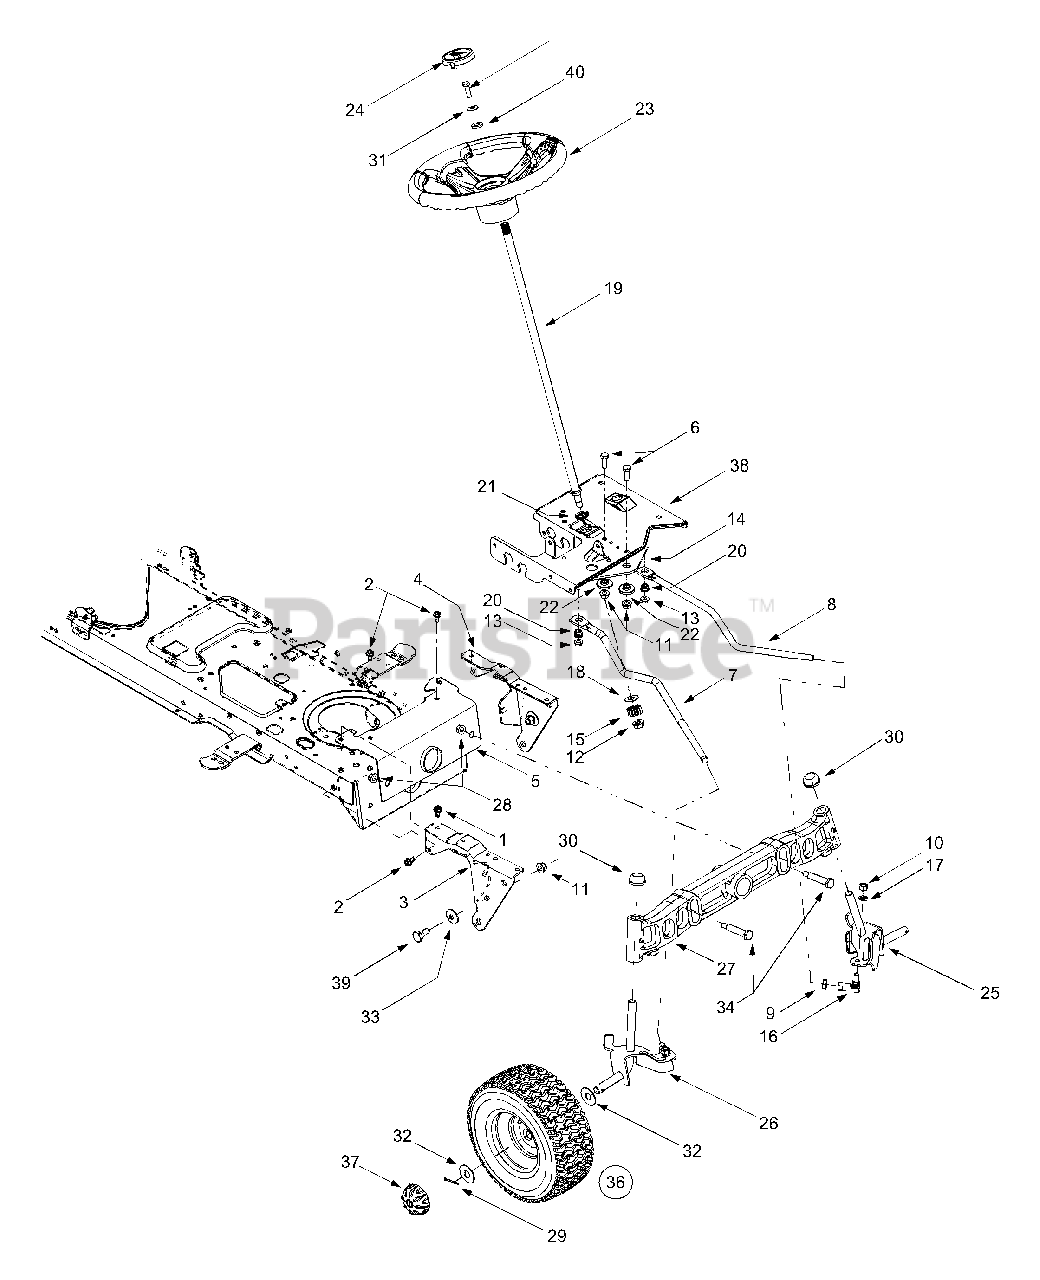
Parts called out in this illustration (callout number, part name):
1	Self-tapping Screw, 5/16-18 x .75
2	Self-tapping Screw, 16-18 x .625
6	Hex Cap Screw, 3/8-16 x 1 (Grade 5)
7	RH Drag Link
8	LH Drag Link
9	Jam Nut, 7/16-20 (Grade 2)
10	Hex Nut, 3/8-24 (Grade 2)
11	Flange Lock Nut, 3/8-16
12	Flange Lock Nut, 7/16-20
13	Flange Lock Nut, 5/16-18
14	Steering Gear, 11/90 Ratio
15	Steering Pinion Gear
16	Ball Joint, 7/16-20
17	Lock Washer, 3/8
18	Flat Washer, .51 x 1.12 x .06
19	Steering Shaft, .625 OD x 24.4
20	Plastic Bushing, .38 ID
21	Hex Flange Bearing, 5/8
22	Shoulder Spacer, .38 ID
23	Steering Wheel, Soft Grip, Three Spoke
24	Steering Wheel Cover
25	LH Axle Assembly (Model 604G)
25	LH Axle Assembly (Model 604H)
26	RH Axle Assembly (Model 604G)
26	RH Axle Assembly (Model 604H)
27	Pivot Bar w/ Fittings (Model 604G)
27	Pivot Bar w/ Fittings (Model 604H)
28	Flange Lock Nut, 3/8-16
29	Cotter Pin
30	Push Cap, .625 (Model 604G)
30	Push Cap, .750 (Model 604H)
31	Bell Washer, .34 x .872
32	Flat Washer, .635 x 1.589 x .06
33	Bell Washer, .39 x 1.13 x .062
34	Shoulder Screw, .5 x 2.2, 3/8-16
35	Hex Bolt, 5/16-18 X 1
37	Hub Cap
39	Shoulder Screw, 3/8-16
40	Flat Washer, .406 x .875 x .105
